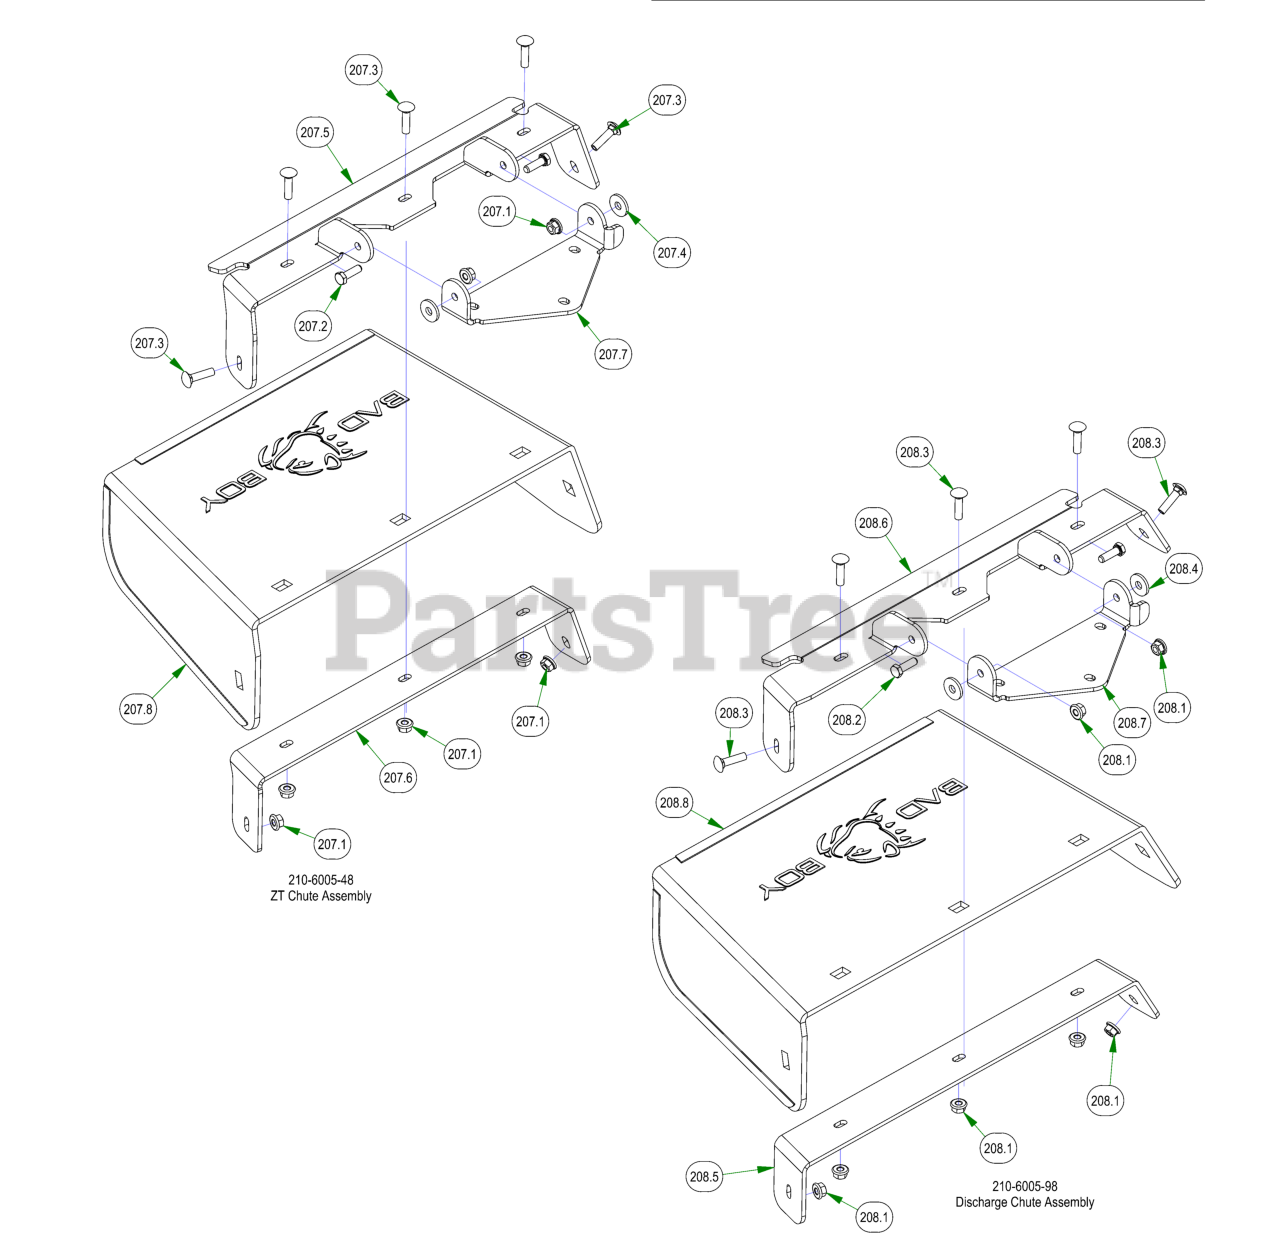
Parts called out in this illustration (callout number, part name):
207	ZT Chute Assembly
207.1	5/16-18 NYLON INSERT FLANGE LOCKNUT ZINC
207.2	5/16-18 X 1 HEX CAP SCREW (GR.5) ZINC
207.3	5/16-18 X 1-1/4 CARRIAGE BOLT ZINC
207.4	.360 ID X .983 OD X .120 THICK FLAT WASHER NYLON
207.5	Discharge Upper Chute Bracket
207.6	Discharge Lower Chute Bracket
207.7	Discharge Chute Hanger (deck mounted)
207.8	Rubber Discharge Chute
208	Discharge Chute Assembly
208.1	5/16-18 NYLON INSERT FLANGE LOCKNUT ZINC
208.2	5/16-18 X 1 HEX CAP SCREW (GR.5) ZINC
208.3	5/16-18 X 1-1/4 CARRIAGE BOLT ZINC
208.4	.360 ID X .983 OD X .120 THICK FLAT WASHER NYLON
208.5	60" Discharge Lower Bracket
208.6	60" Discharge Chute Upper Hanger
208.7	Discharge Chute Hanger (deck mounted)
208.8	Rubber Discharge Chute
